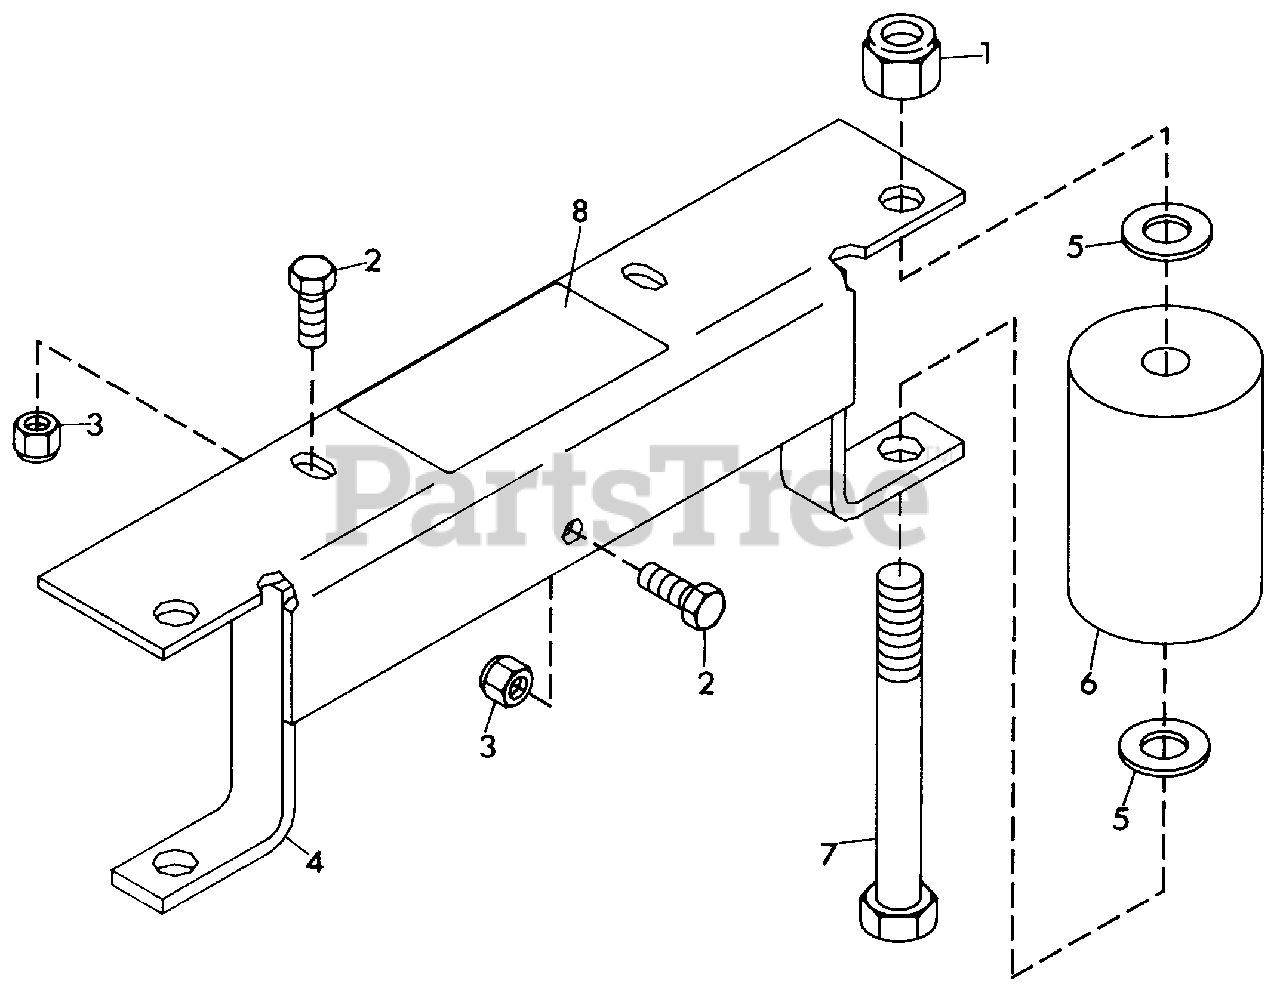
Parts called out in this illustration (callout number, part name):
1	NUT, LOCK 5/8-11
2	BOLT, HEX 3/8-16X1.00
3	NUT, LOCK 3/8-16
4	WELDMENT, ROLLER BRACKET
5	WASHER, FLAT .656X1.250X.100
6	ROLLER, GAGE
7	BOLT, HEX 5/8-11X5.50
8	DECAL, DANGER FOOT
